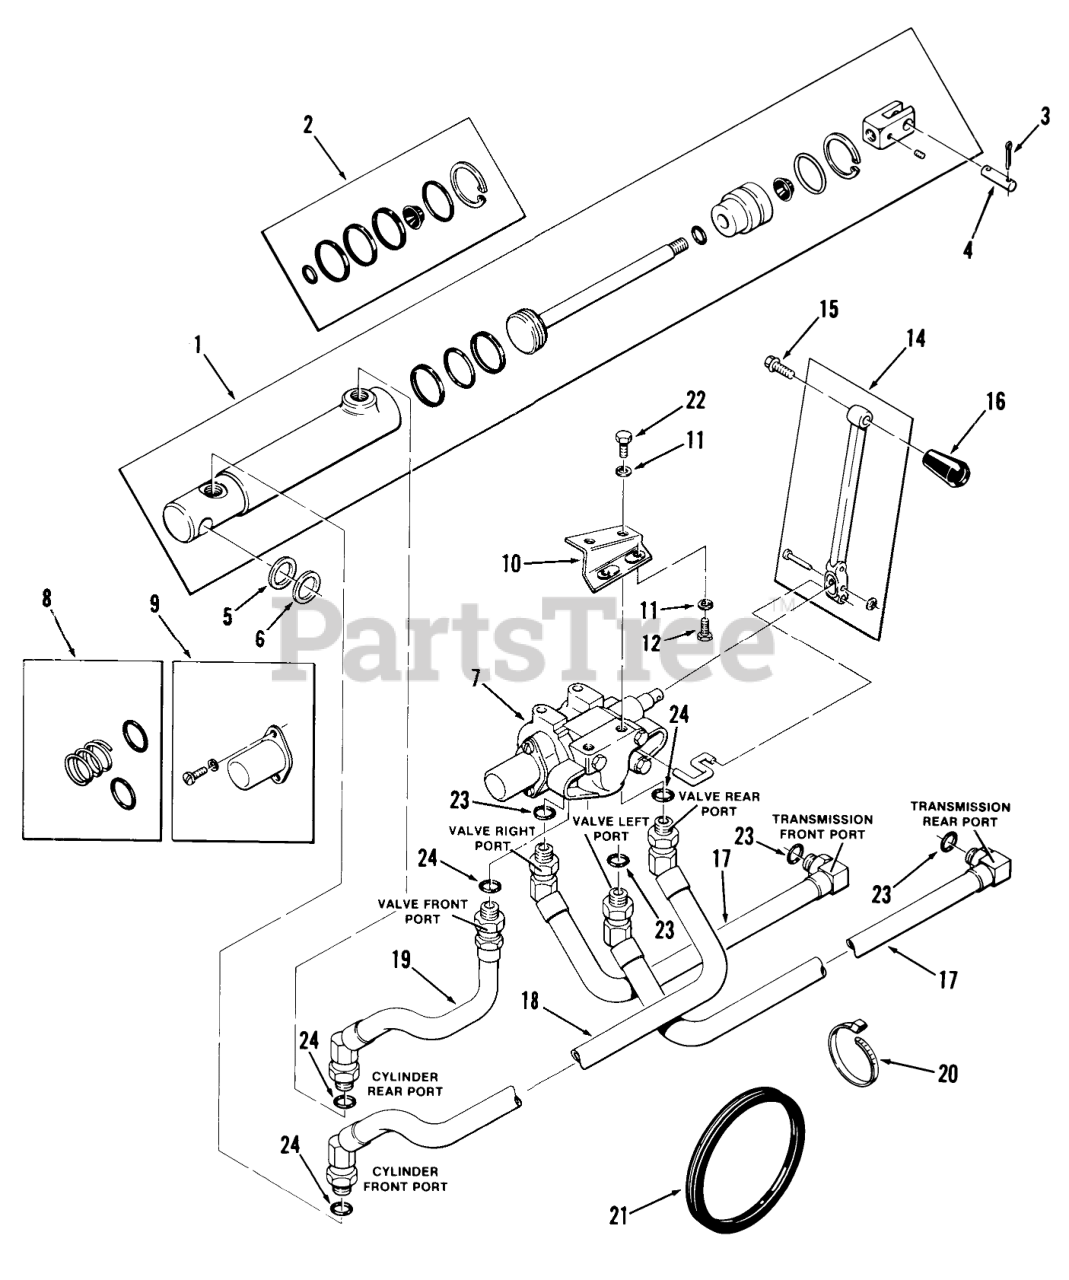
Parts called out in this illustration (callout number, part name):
1	Hydraulic Cylinder
2	S/A O-RING&GASKET AS
4	PIN
5	WASHER
6	Spacer
7	Hydraulic Valve C-141, C-161, C-161 Twin Only
8	0-Ring Kit-S.A.
9	Spool Cap Kit
10	Mounting Bracket
11	Lockwasher
12	Bolt
13	Lockwasher
14	S/A HANDLE&HARDWARE
15	SCREW
17	ASSY-HYDRAULIC HOSE
18	Hose-Valve To Cylinder
19	Hose-Valve To Cylinder
20	PLASTIC TIE
21	GROMMET
22	Bolt
23	0-Ring
24	O RING
